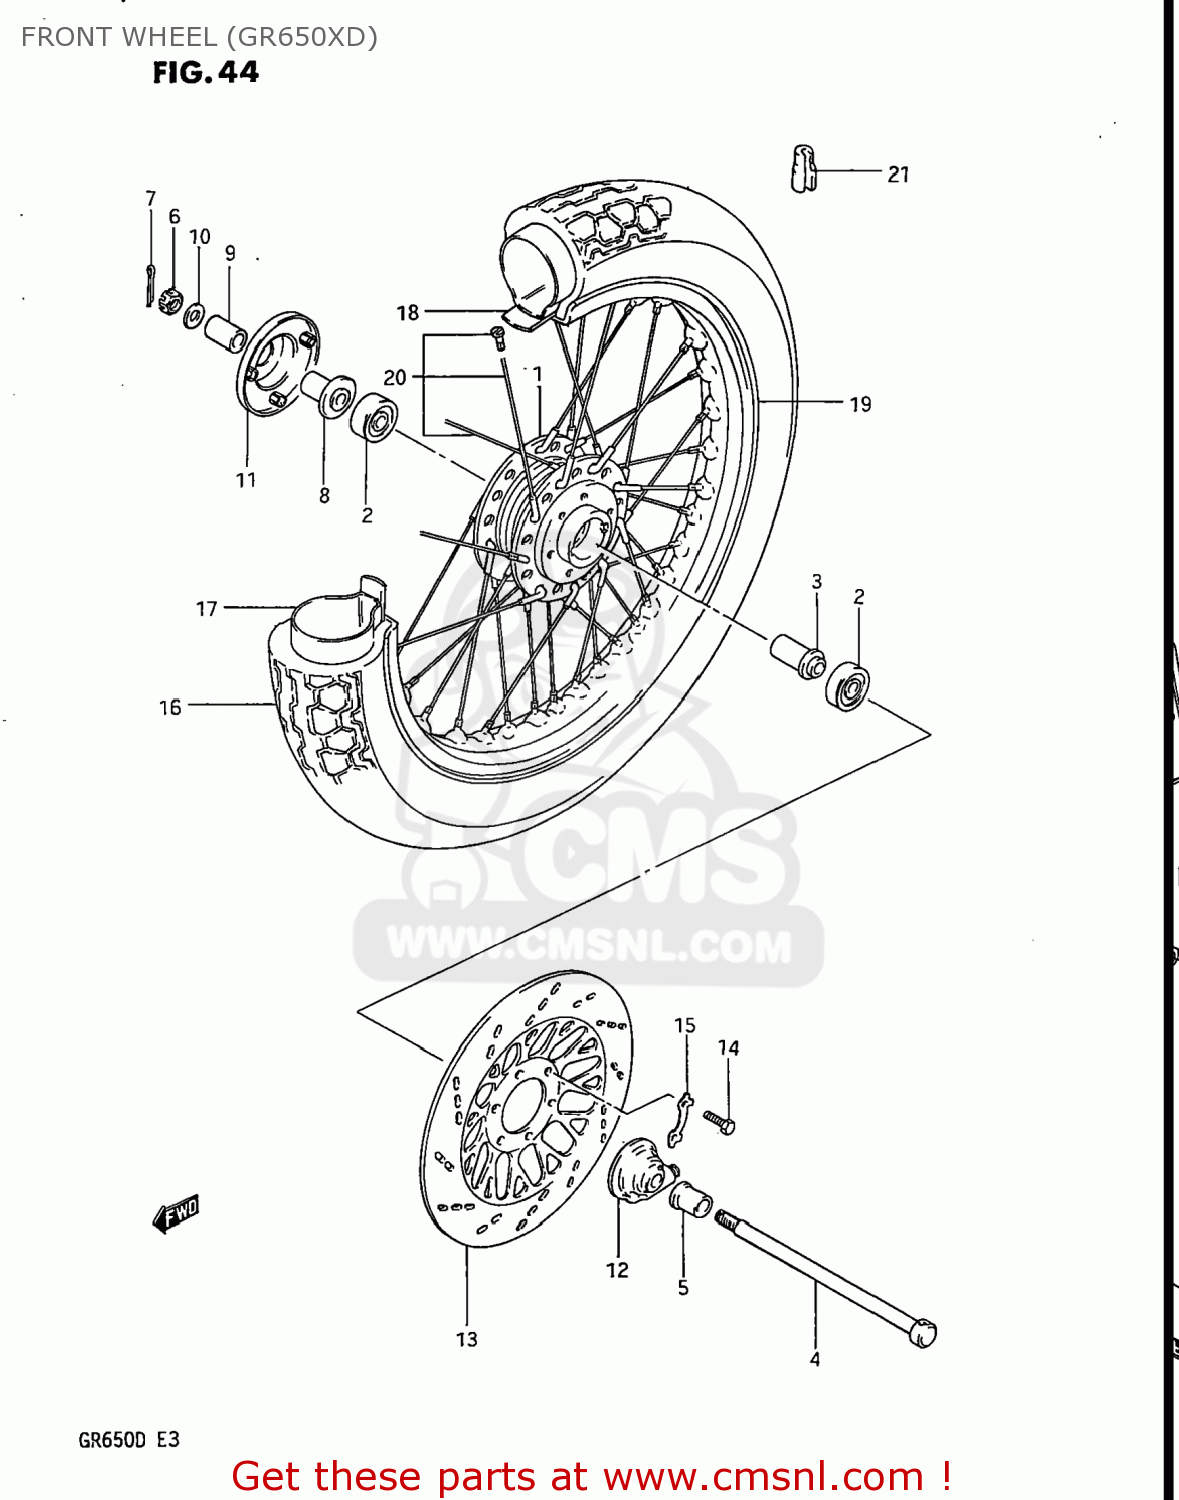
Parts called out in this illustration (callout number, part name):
1	DRUM,FRONT HUB
2	BEARING
3	SPACER,FR HUB BEARING
4	AXLE,FR
5	SPACER,FRONT AXLE,RIGHT
6	NUT 12MM
7	COTTER PIN
8	SPACER,FR AXLE,R
9	SPACER,FRONT AXLE,RIGHT
10	WASHER
11	COVER,FR HUB,R
12	BOX ASSY,SPEEDOMETER GEAR
13	DISC,FR BRAKE,L
14	BOLT(8X25)
15	WASHER
16	TIRE,FRONT
17	TUBE,INNER
18	PROTECTOR,WHL INR TUBE
19	RIM,FRONT WHEEL (1.85X19)
20	SPOKE SET,FRONT
21	BALANCER,WHEEL (B)
